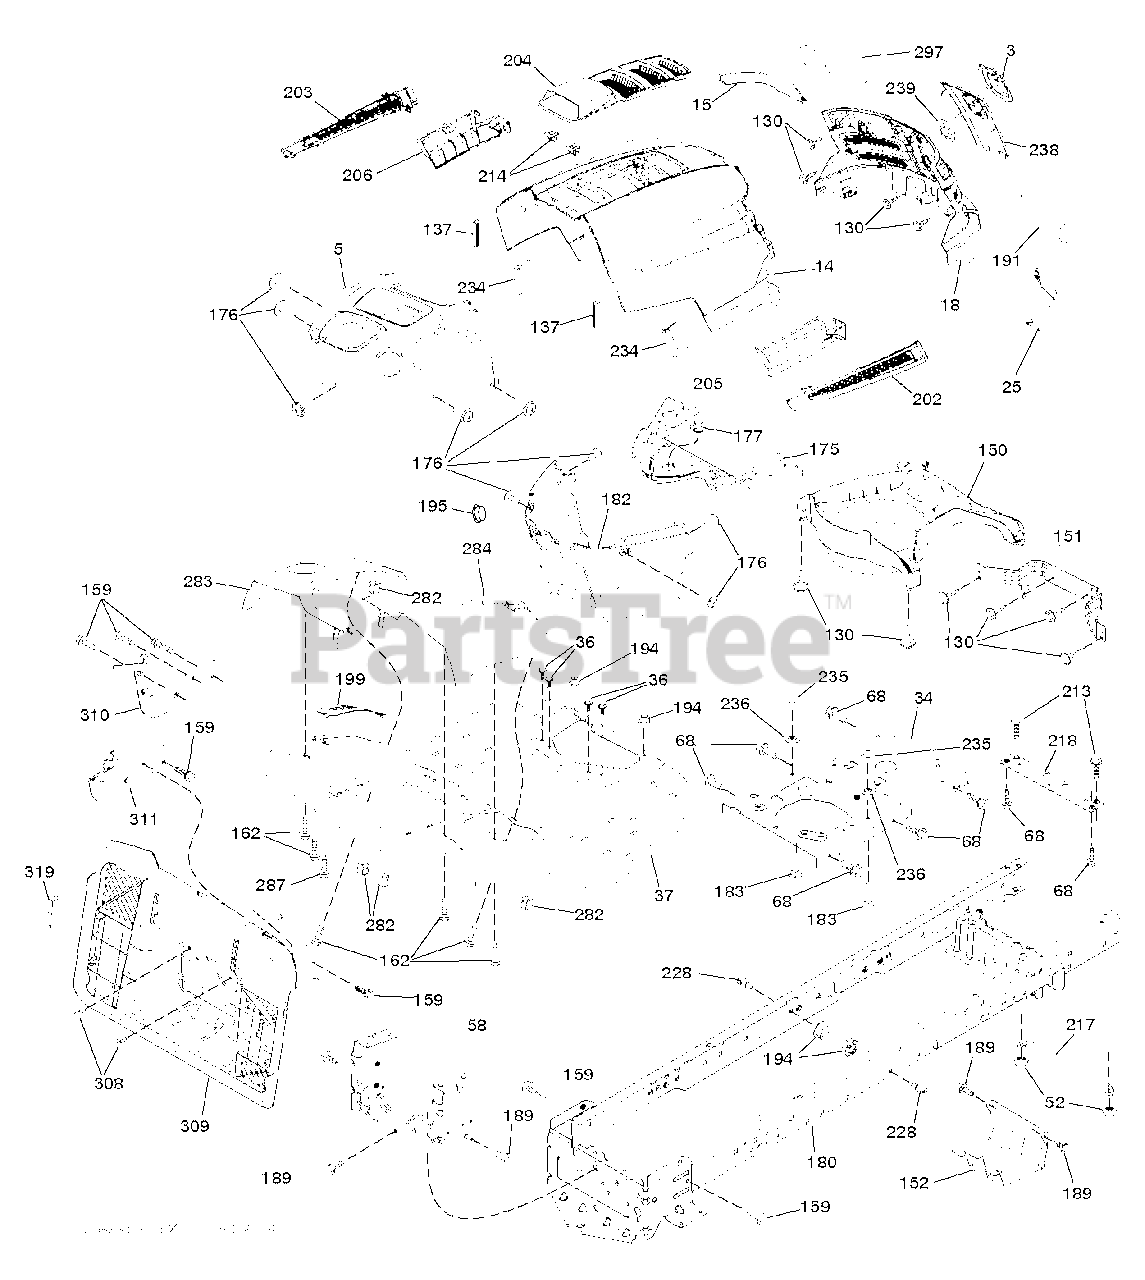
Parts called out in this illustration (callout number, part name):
3	RP LOGO
5	SUBASM.DASH.UPPER.W/BUMPER
14	HOOD.HUSQVARNA.LT.ORANGE
15	LENS.HUSQVARNA LT.RH
18	GRILLE.SVC.HUSQVARNA.GREY
25	LENS.HUSQVARNA LT.RH
34	PLATE.ENGINE.WELDED.CHASSIS
36	SCREW 5/16"
37	FENDER.TEX.SRD.CRD.BASE
52	LOCKNUT
58	DRAWBAR UPPER 2PC SMALL FENDER
68	SCREW LT
130	SCREW.#10 X 0.750.BOS
137	BUMPER DASH
151	BRACKET PIVOT
152	SHIELD.BROWNING.W/TEX
159	SCREW, 3/8-16X3/4
162	SCREW.HI-LO.CONSOLE
175	CROSSMEMBER
176	SCREW.#10-24X5/8.RN.QU
177	BUSHING STEERING
180	CHASSIS.WLDMNT.14GA.2PC.18".TI
182	DASH.LOWER.PREDATOR LT
183	BOLT.5/16-18X1-1/4 FULL THD
189	SCREW
191	INSERT.REFLECTIVE.RH.
194	NUT LOCK HEX FLANGE 5/16-18
195	PLUG.TEX.DASH.SVC.MINDER.GREY
199	PLATE DECK LIFT
202	VENT.SIDE.HUSQVARNA.LT.RT
203	VENT.SIDE.HUSQVARNA.LT.LFT
204	SUBASM.TOP.VENT.HUSQ.LT
205	SKIRT.SIDE.HUSQVARNA.LT.RT
206	SKIRT.SIDE.HUSQVARNA.LT.LEFT
213	BOLT
214	CLIP.RETAINER.TINNER.
217	ROD.PIVOT.HOOD
218	X-PIECE.HOOD.STOP.NON/
228	STUD.FASTNER.W/ANTI-ROTATE
234	BUMPER.HOOD.TEX.HUSQVARNA
235	SPACER FENDER
236	NUT.CENTERLOCK.5/16-
238	TRIM.HUSQ LT.668
282	CLIP.RETAINER.CONSOLE.LT.HUSQ
283	CONSL.DECKLIFT.LH.SRD.TEX.CRD
284	CONSL.SHIFT.GEAR.RH.SRD.GREY
287	SCREW 1/4X20
297	INSERT REFLECTIVE
308	BOLT, 5/16-18 X 1 3/4
309	BACKPLATE.BAGGER.V2.SRD
319	BRACKET.ACTUATOR.BAGGER.SRD
